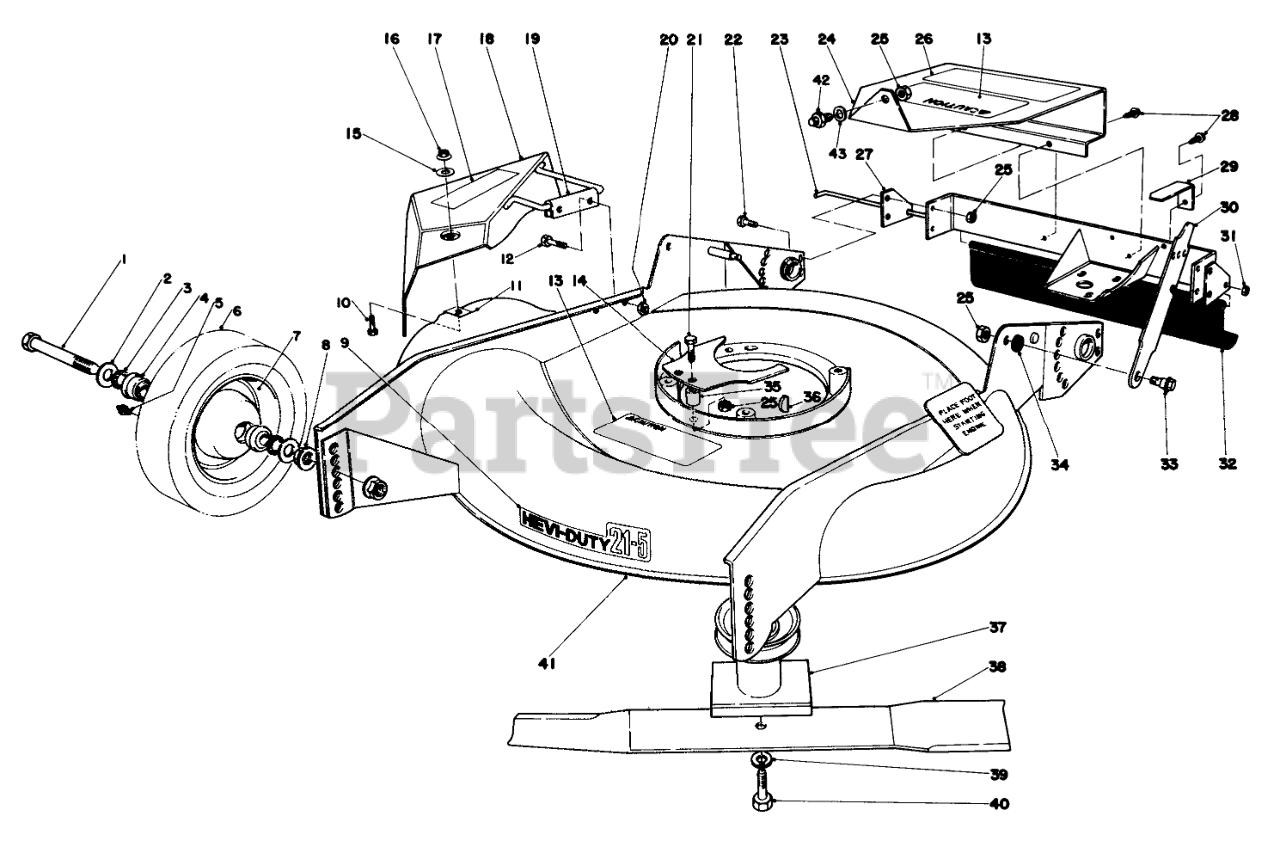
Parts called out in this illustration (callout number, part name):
1	SCREW-HH
2	WASHER-FLAT
3	FELT WASHER
4	BEARING-BALL
5	FITTING-GREASE
7	Wheel & Tire Assembly (Incl. Ref. #4-6)
8	NUT-HF
9	Decal-Hevi-Duty 21-5
10	SCREW-HH
11	NUT-SPEED
12	SCREW-HH
13	DECAL SAF INST
14	Belt Guide-Front
15	WASHER-FLAT
16	NUT-LOCK, HHF
17	Decal-Deflector
18	Deflector
19	Hinge-U Bracket
20	NUT-LOCK
21	SCREW-HH
22	SCREW-HH
23	Safety Shield Rod
24	Shroud
25	Nut
26	Decal
27	Bracket-Safety Shield
28	Screw
29	Belt Guide-Rear
30	Latch
31	NUT-LOCK, NI
32	Rear Safety Shield
33	SCREW-SHOULDER
34	SPACER
35	BELT GUIDE SPACER
36	KEY-WOODRUFF
37	Yoke Bushing
38	Blade
39	WASHER-LOCK
40	Place Bolt
41	Housing
42	Head Bolt Stud
43	Washer
